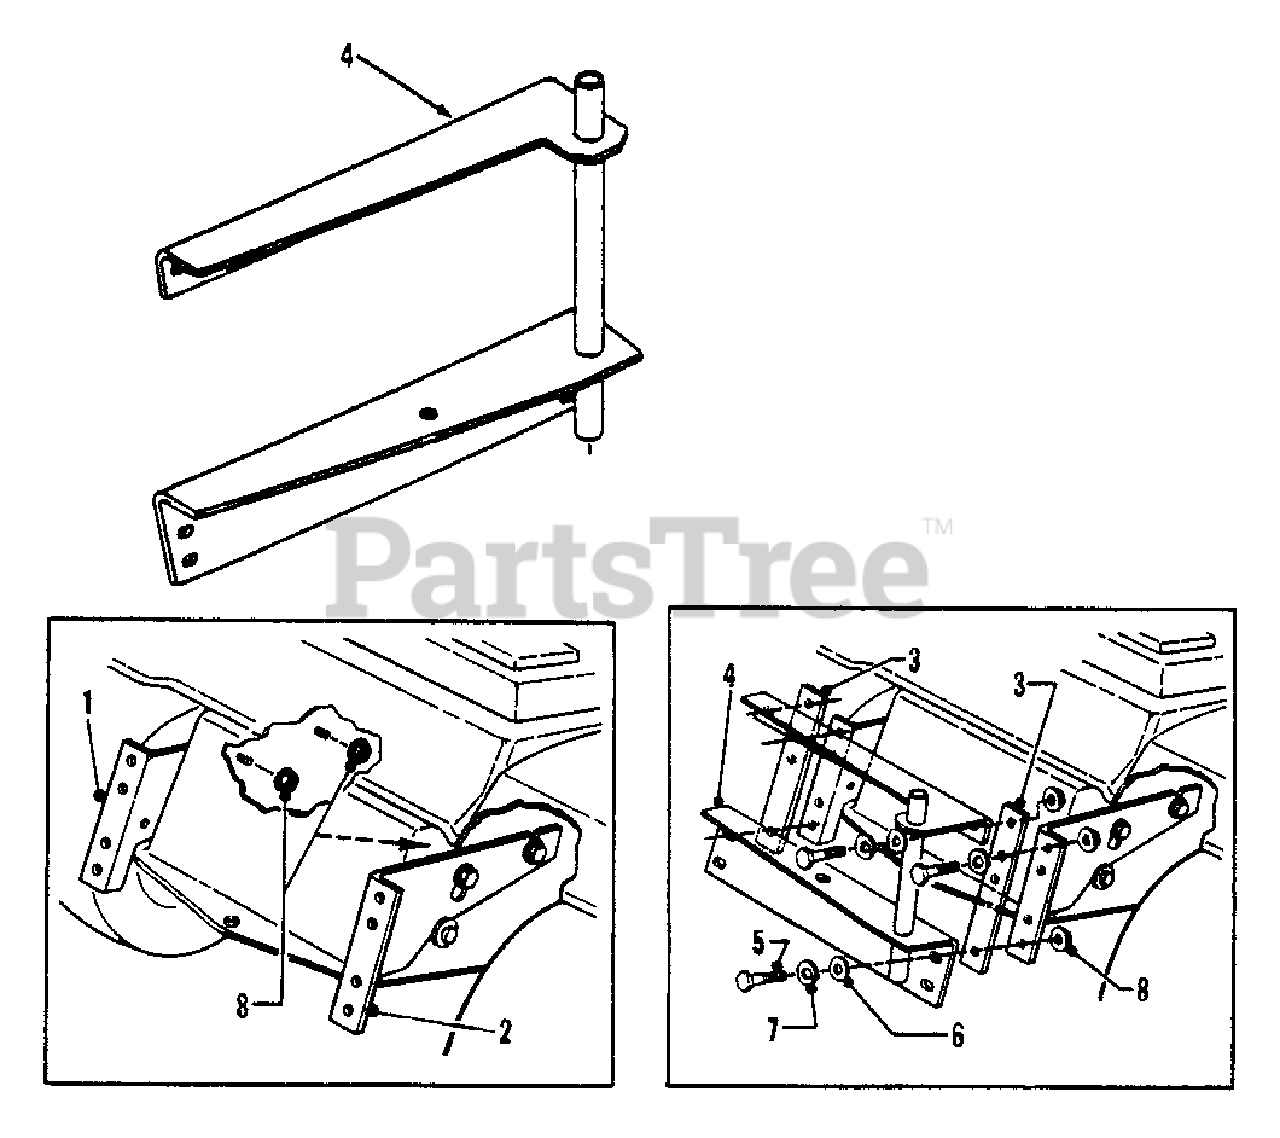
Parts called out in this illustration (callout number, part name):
1	SUPPORT, Stand-up Tube L.H.
2	SUPPORT, Stand-up Tube R.H.
3	ADAPTER, Alignment
4	WELDMENT, Adapter
5	BOLT, 5/16-18 x 1-1/4" Hex Head, Grade 8
6	WASHER, 5/16" Flat, Grade 5
7	WASHER, 5/16" Split Lock
8	NUT, 5/16-18 Hex, Grade 5
